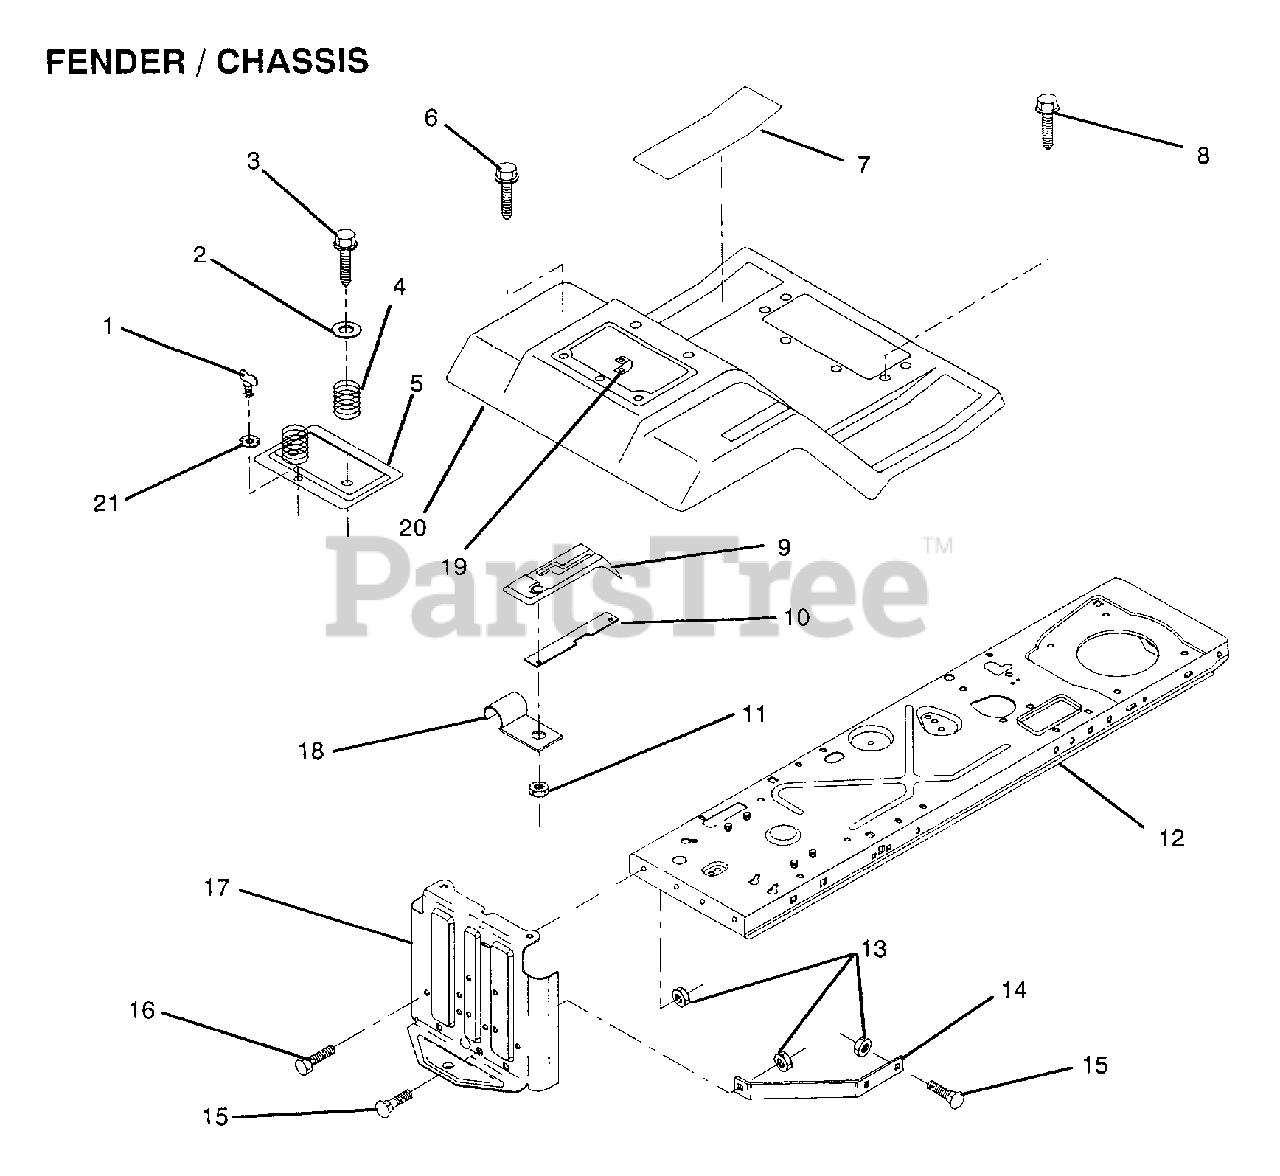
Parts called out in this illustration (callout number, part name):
1	STUD.1/4.TURN
2	WASHER
3	SCREW
4	SPRING COMPRESSIO
5	"DOOR,FENDER T"
6	SCREW LT
7	PAD FOOTREST
8	SCREW
9	"CONSOLE,SHIFT CON"
10	BAR SHIFT LOCK
12	FRAME ASS'Y
14	"BRACE,DRAWBAR "
15	BOLT
16	BOLT
17	DRAWBAR
18	"CLIP,INSULATOR"
19	RECEPTACLE LT
20	"FENDER,FOOTREST T"
21	RETAINER LT
